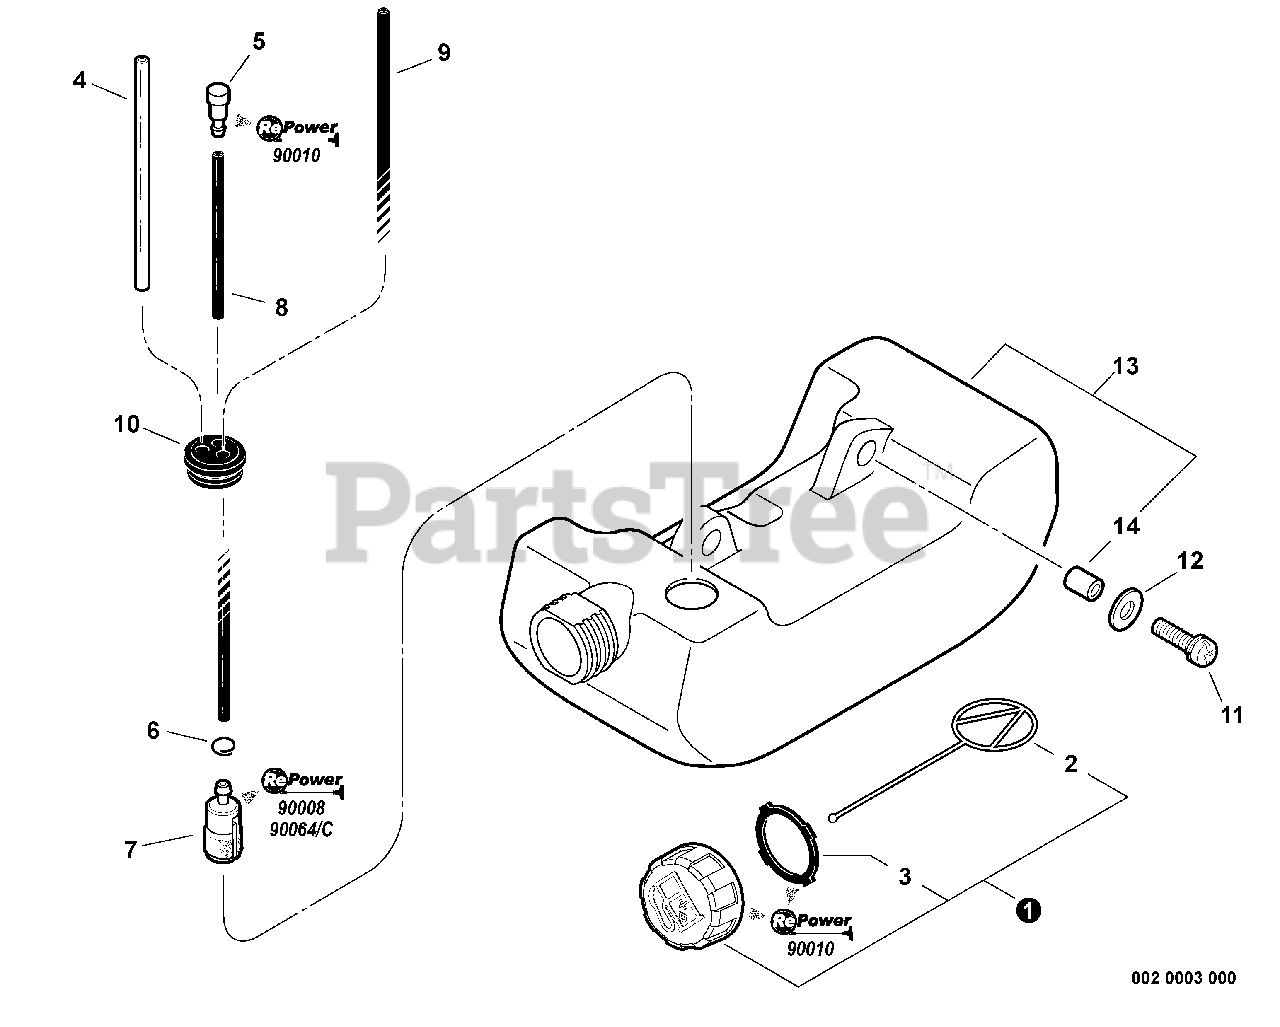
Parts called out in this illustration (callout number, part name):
1	CAP ASSY, FUEL
2	CONNECTOR, CAP L= 100 MM
3	GASKET, FUEL CAP
4	PIPE, FUEL RETURN 3×6×90 MM CLEAR
5	VENT ASSY
6	CLIP 6 MM
7	FILTER, FUEL
8	PIPE, FUEL 3x-5x-70 BLACK
9	PIPE, FUEL 3x-5x-180
10	GROMMET, FUEL
11	BOLT 5×16
12	WASHER 5.5×12×0.8
13	TANK, FUEL
14	SPACER 6.2×7.8×6
15	CAP/VENT KIT - REPOWER
